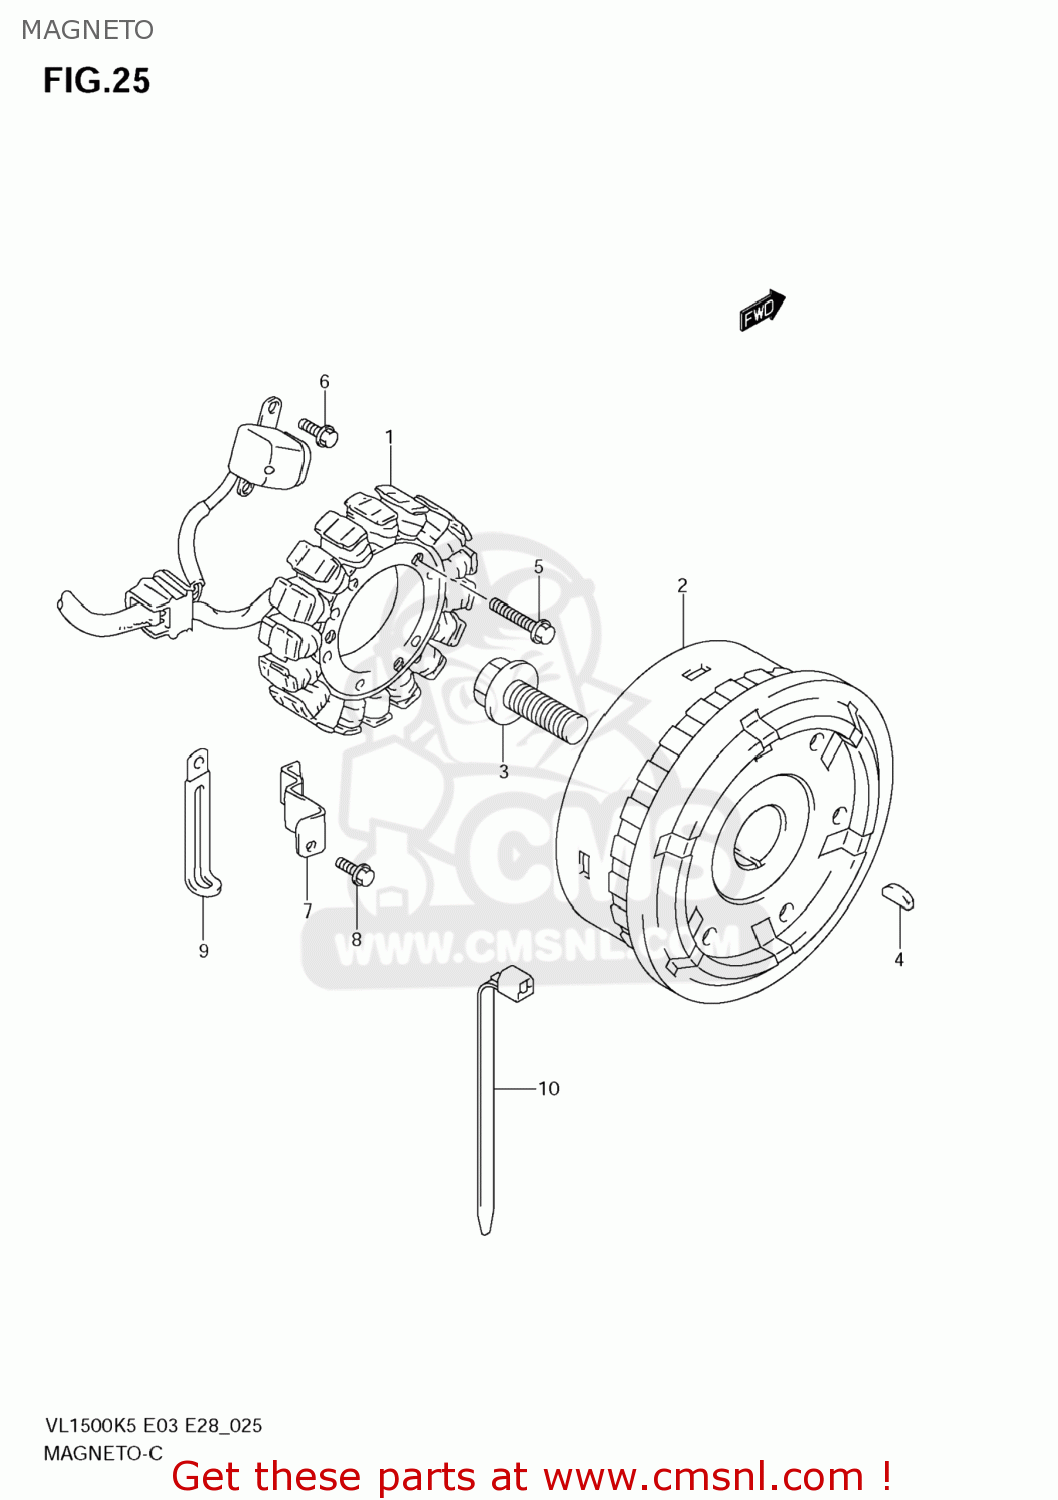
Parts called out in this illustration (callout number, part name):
1	STATOR ASSY
2	ROTOR ASSY
3	BOLT(14X43)
4	KEY
5	BOLT
6	BOLT
7	CLAMP,MAGNETO LEAD WIRE
8	BOLT
9	CLAMP(L:45)
10	CLAMP(L:165)
